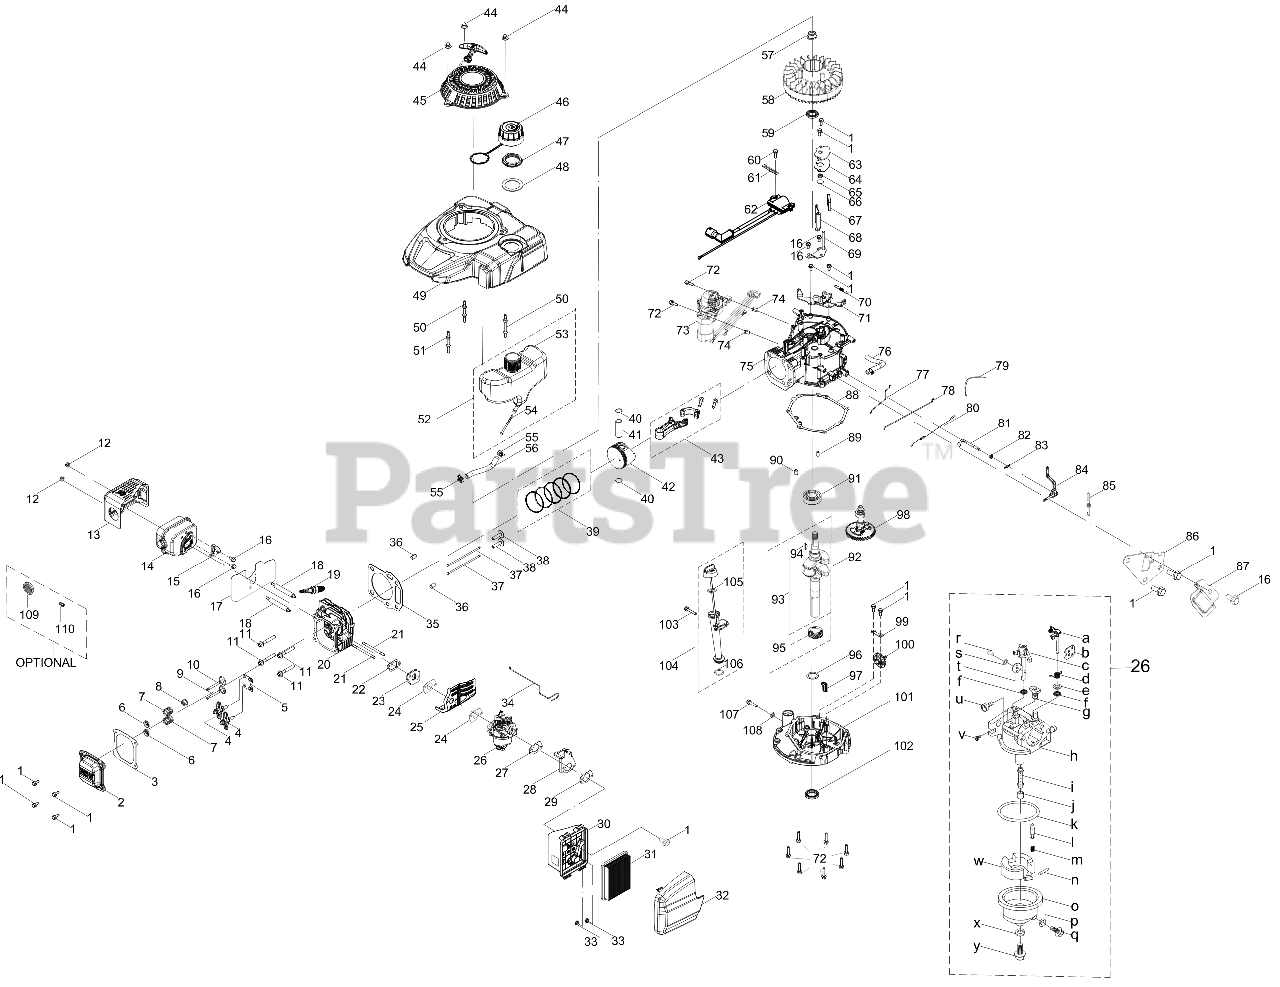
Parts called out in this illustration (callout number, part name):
1	BOLT M6-1 x 14 GR8.8
2	VALVE COVER
3	VALVE COVER GASKET
4	ROCKER ARM ASSEMBLY
5	PUSH ROD GUIDE
6	VALVE SPRING RETAINER
7	VALVE SPRING
8	INTAKE VALVE SEAL
9	EXHAUST VALVE
10	INTAKE VALVE
11	BOLT-M8 x 54
13	MUFFLER SHIELD
14	MUFFLER ASSEMBLY
15	THERMOSTAT
16	BOLT M6-1 x 12 GR8.8
17	MUFFLER GASKET
18	STUD M6-1 x 95
19	SPARK PLUG
20	CYLINDER HEAD
21	STUD M6 x 90
22	CARBURETOR INSULATOR GASKET
23	CARBURETOR INSULATOR
24	CARBURETOR GASKET
25	CARBURETOR HEAT SHIELD
26	CARBURETOR
27	AIR FILTER BRACKET GASKET
28	AIR FILTER BRACKET
29	AIR FILTER BASE GASKET
30	AIR FILTER BASE
31	AIR FILTER
32	AIR FILTER COVER
34	CHOKE TEMP CONTROL LINKAGE
35	CYLINDER HEAD GASKET
38	TAPPET
39	PISTON RING SET
40	SNAP RING-PISTON PIN
41	PISTON
42	PISTON PIN
43	CONNECTING ROD ASSEMBLY
44	ACORN NUT
45	RECOIL STARTER ASSEMBLY
46	FUEL CAP W/TETHER
47	FUEL TANK NUT
48	FUEL TANK UPPER GROMMET
49	ENGINE SHROUD W/O IGNITION SWITCH
50	STARTER/SHROUD REAR STUD
51	STARTER/SHROUD FRONT STUD
52	FUEL TANK ASSEMBLY
53	FUEL TANK
54	FUEL FILTER
55	HOSE CLAMP
56	FUEL HOSE
57	FLYWHEEL NUT
58	FLYWHEEL
59	CRANKSHAFT SEAL
60	BOLT M6-1 x 20 GR8.8
61	FLEXIBLE CLAMP
62	IGNITION COIL ASSEMBLY
63	BREATHER COVER PLATE
64	BREATHER GASKET
65	BREATHER VALVE SPRING
66	BREATHER VALVE
67	BREATHER SCREEN
68	AIR VANE
69	AIR VANE BRACKET
70	ENGINE BRAKE SPRING
71	ENGINE BRAKE ASSEMBLY
72	BOLT-M6-1 x 28 GR8.8
73	ELECTRIC STARTER ASSEMBLY
74	DOWEL PIN
75	CRANKCASE
76	BREATHER HOSE ASSEMBLY
77	CHOKE LINKAGE
78	THROTTLE LINKAGE
79	CABLE TIE - 3 x 150
80	THROTTLE LINKAGE SPRING
81	GOVERNOR ARM SHAFT
82	GOVERNOR SEAL
83	COTTER PIN
84	GOVERNOR ARM ASSEMBLY
85	GOVERNOR SPRING
86	COMPONENT BRACKET
87	GOVERNOR SHIELD
88	CRANKCASE COVER GASKET
89	DOWEL PIN
90	DOWEL PIN
92	CRANKSHAFT ASSEMBLY
93	CRANKSHAFT
94	FLYWHEEL KEY
95	CRANKSHAFT TIMING GEAR
96	THRUST WASHER
97	OIL RETURN SEAL
98	CAMSHAFT ASSEMBLY
99	GOVERNOR GEAR MOUNTING PLATE
100	GOVERNOR GEAR/SHAFT ASSEMBLY
101	CRANKCASE COVER
102	LOWER CRANKSHAFT SEAL
103	BOLT M6-1 x 35 GR8.8
104	OIL DIPSTICK ASSEMBLY
105	O-RING
107	OIL DRAIN PLUG
108	WASHER
109	SPARK ARRESTOR
110	SCREW M3.5 x 9.5
S	Throttle Plate Lock Washer
